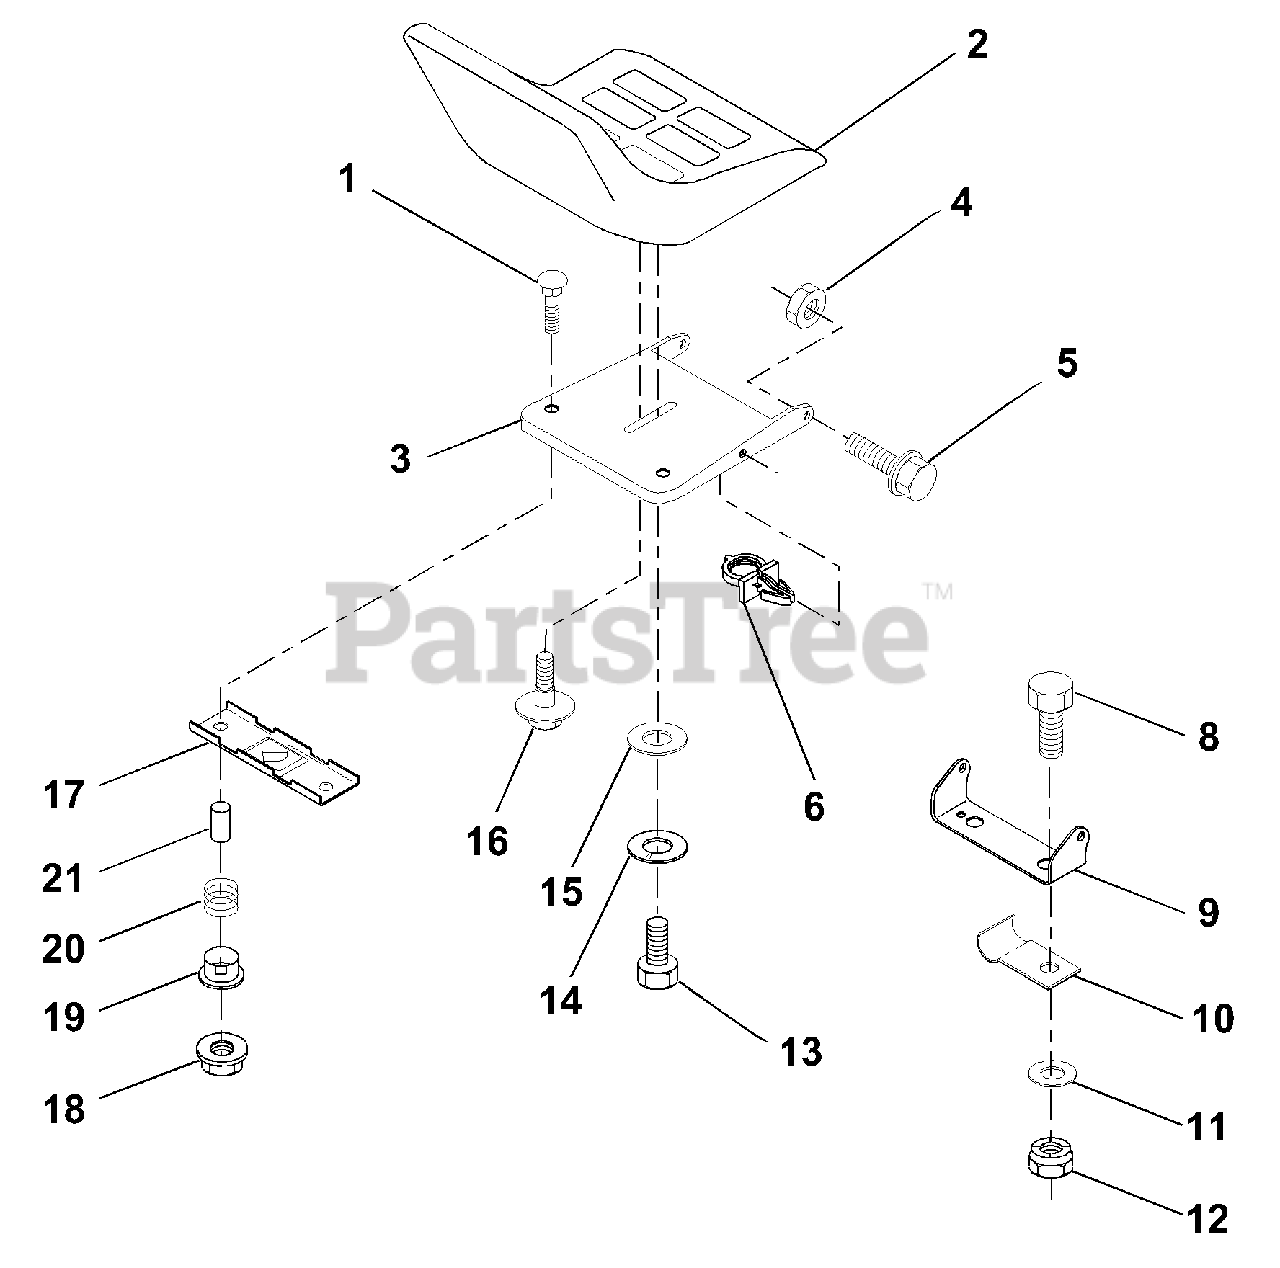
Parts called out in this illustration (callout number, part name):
1	Bolt, Carriage 1/4-20 x 1-3/8
2	Seat
3	Pan, Seat
4	Nut, Crownlock 5/16-18
5	Bolt, Shoulder 5/16-18 UNC
6	Clip, Push-In Hinged
8	Bolt, Fin Hex 3/8-16 UNC x 3/4
9	Bracket, Pivot Seat
10	Clip, Insulated
11	Washer 12/32 x 2 x 10 Ga.
12	Nut, Crownlock 3/8-16 UNC
13	Bolt Hex 1/2-13 x 7/8
14	Washer Lock Hvy. Hlicl Spring 1/2
15	Washer, 17/32 x 1-3/16 x 12 Ga.
16	Bolt, Shoulder
17	Bracket, Switch, Mounting
18	Nut, Hex Large Flange Lock
19	Bushing, Snap
20	Spring, Compression
21	Spacer, Split 28 Id. x .88 Lg.
